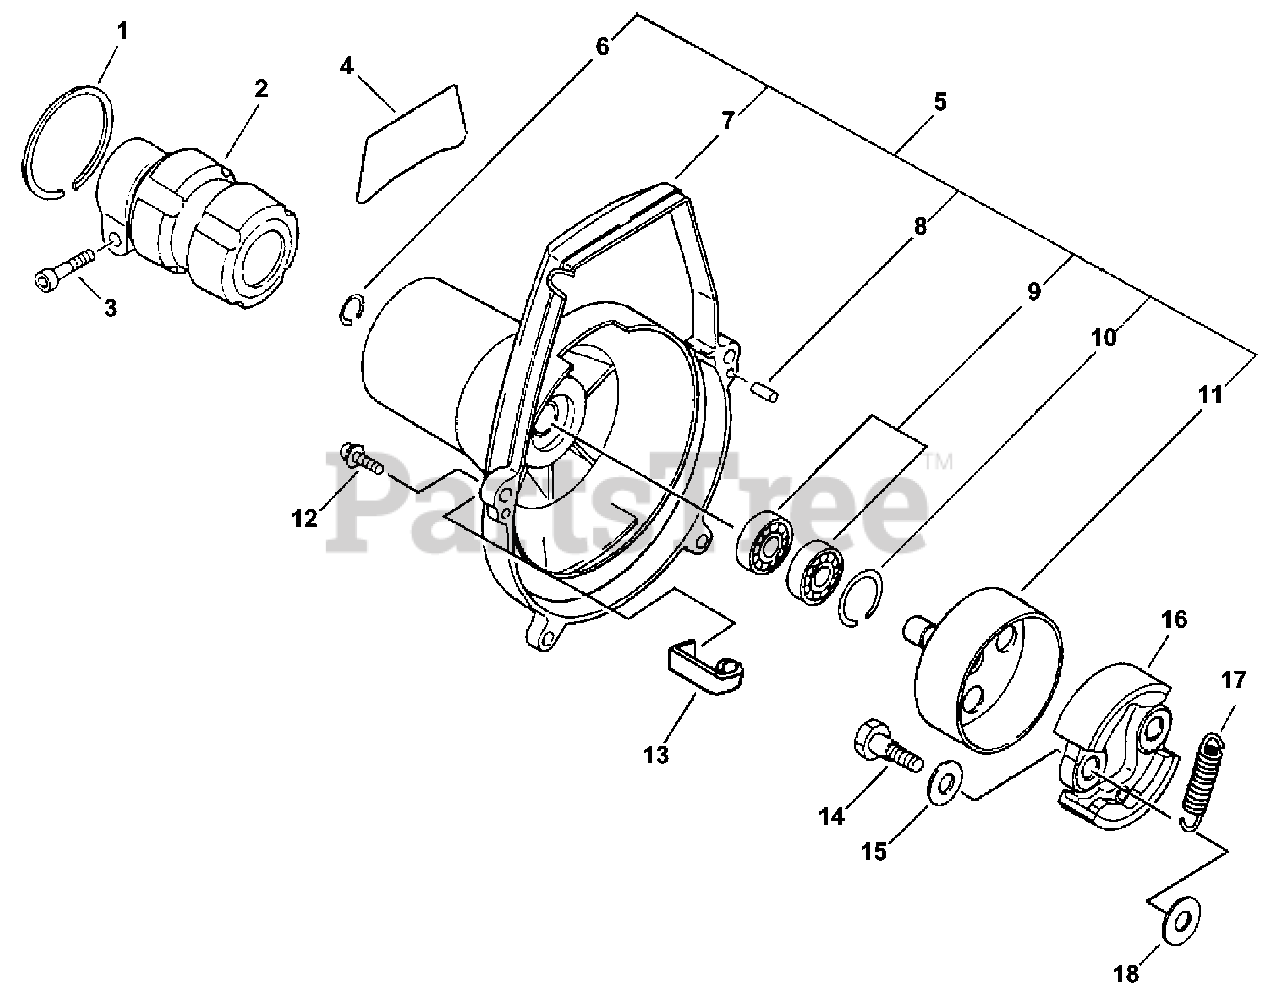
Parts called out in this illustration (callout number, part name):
1	RING, SNAP Ø42
2	HOLDER, MAIN PIPE
3	BOLT 5×28
4	LABEL, MODEL
5	COVER ASSY, FAN - GRAY
6	RING, RETAINING - 12
7	COVER, FAN
8	PIN, LOCATING 4
9	BEARING, BALL 6001
10	RING, SNAP 28
11	DRUM, CLUTCH
12	BOLT 5×18
14	BOLT, CLUTCH 8×7.9×M6
15	WASHER, SPRING 8.5×16×0.5
16	SHOE, CLUTCH
17	SPRING, CLUTCH
18	WASHER 6.2×19×1.0
